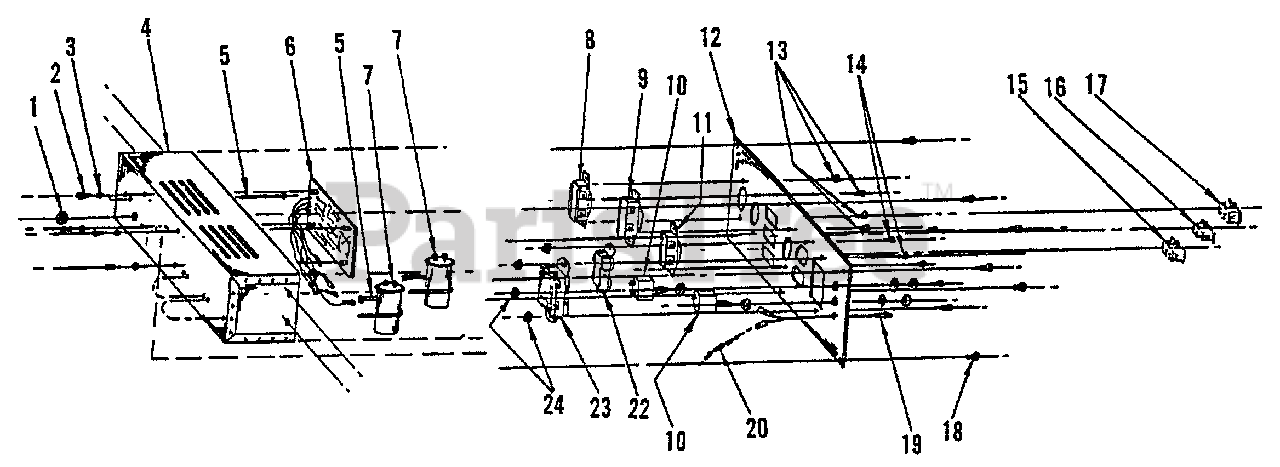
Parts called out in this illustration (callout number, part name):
1	GROMMET
2	6-32X 1/4 RHS
3	LOCKWASHER - 6
4	BOX, CONTROL
5	TIE, CABLE
6	CIRCUIT, ECHO-MIZER
7	CAPACITOR - 50UF 370V
8	LOCK, TWIST 20A/125V/250V
9	LOCK, TWIST 20A/240V
10	BREAKER, CIRCUIT - 30A/250V
11	LOCK, TWIST - 30A/125V
12	PANEL SILKSCREEN
13	6-32X3/8 RHS
14	8-32X3/8 RHS
15	SWITCH, ECHO-MISER
16	SWITCH, FULL POWER
17	SWITCH, IGNITION
18	SCREW - 10-24
19	INDICATOR - LOW OIL
20	RESISTOR ASSY
22	DUPLEX, 15A/125V
23	GFCI - 15A/125V
24	NUT - 8-32 -- KEPS
